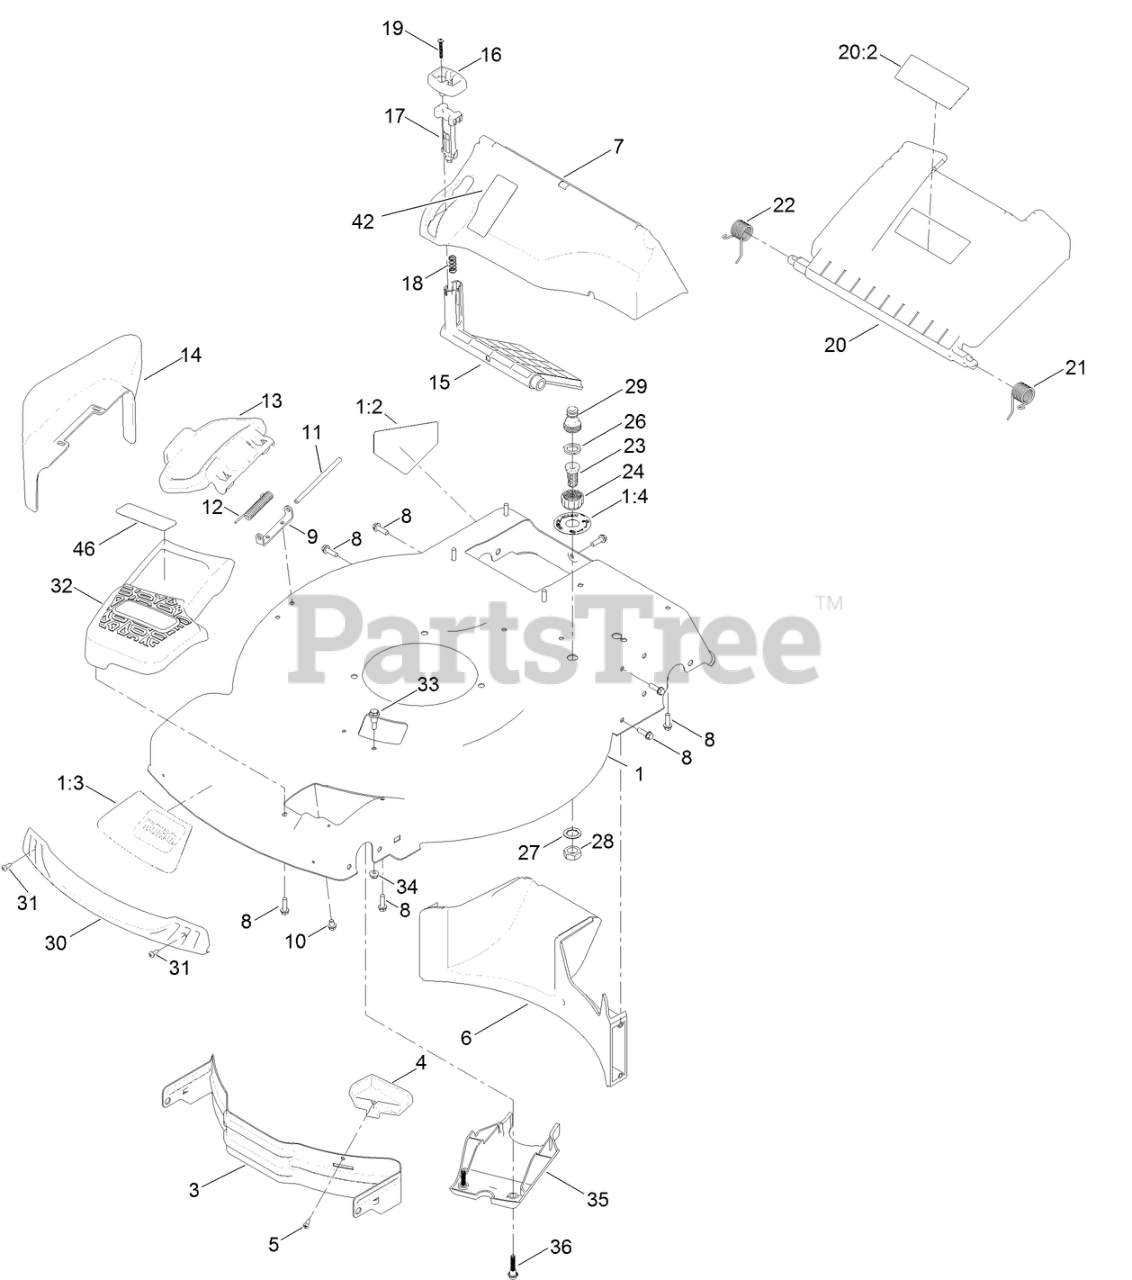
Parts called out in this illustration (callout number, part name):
1	HOUSING ASM
1:2	DECAL-DANGER
1:3	DECAL-DECK
1:4	DECAL-PORT, WASHOUT
3	BAFFLE-FRONT
4	KICKER-FRONT
5	SCREW-PPH
6	BAFFLE-REAR
7	CHUTE-RECYCLE
8	SCREW-HWH
9	BRACKET-COVER
10	SCREW-HWH
12	SPRING-TORSION
13	DEFLECTOR-SIDE
14	CHUTE-DISCHARGE, SIDE
15	DEFLECTOR-RECYCLE
16	KNOB-RECYCLE
17	LATCH-RECYCLE
18	SPRING-COMPRESSION
19	SCREW-PPH
20:2	DECAL-WARNING
21	SPRING-TORSION
22	SPRING-TORSION
23	PORT-WASHOUT
24	COUPLING-HOSE, WASHOUT PORT
26	WASHER-SEAL, WASHOUT PORT
27	WASHER-LOCK
28	NUT-JAM
29	ADAPTER-CONNECT, QUICK
30	BUMPER
31	SCREW-FORMING, THREAD
32	COVER-BELT, FRONT
33	BOLT-SHOULDER
34	NUT-LOCK, NI
35	COVER-BELT, FRONT
36	SCREW-SHOULDER, HHF
46	DECAL-COVER
